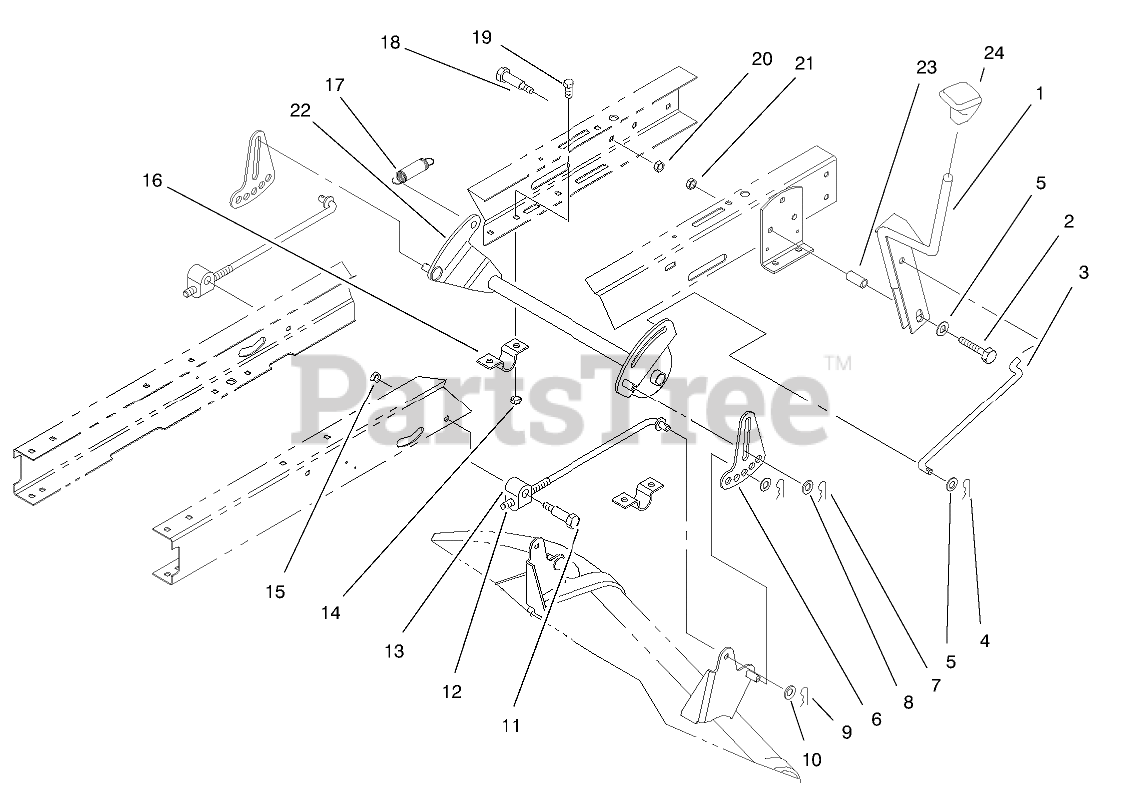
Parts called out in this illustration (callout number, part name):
1	HOC LEVER ASM
2	SCREW-HH
3	LINK-HOC
4	PIN-COTTER
5	WASHER-FLAT
6	LINK-ADJUSTING, HOC
7	PIN-COTTER
8	WASHER-HARDENED
9	PIN-COTTER
10	WASHER-FLAT
11	SCREW-SHOULDER, HH
12	ROD-HANGER, REAR
13	TRUNNION-HOC
14	NUT-LOCK, NI
15	NUT-LOCK, NI
16	CLAMP-PIVOT, HOC
17	SPRING-EXTENSION
18	SCREW-SHOULDER, HH
19	SCREW-HH
20	NUT-LOCK, NI
21	NUT-LOCK, NI
22	PIVOT ASM
23	SPACER
24	KNOB-SHIFT
